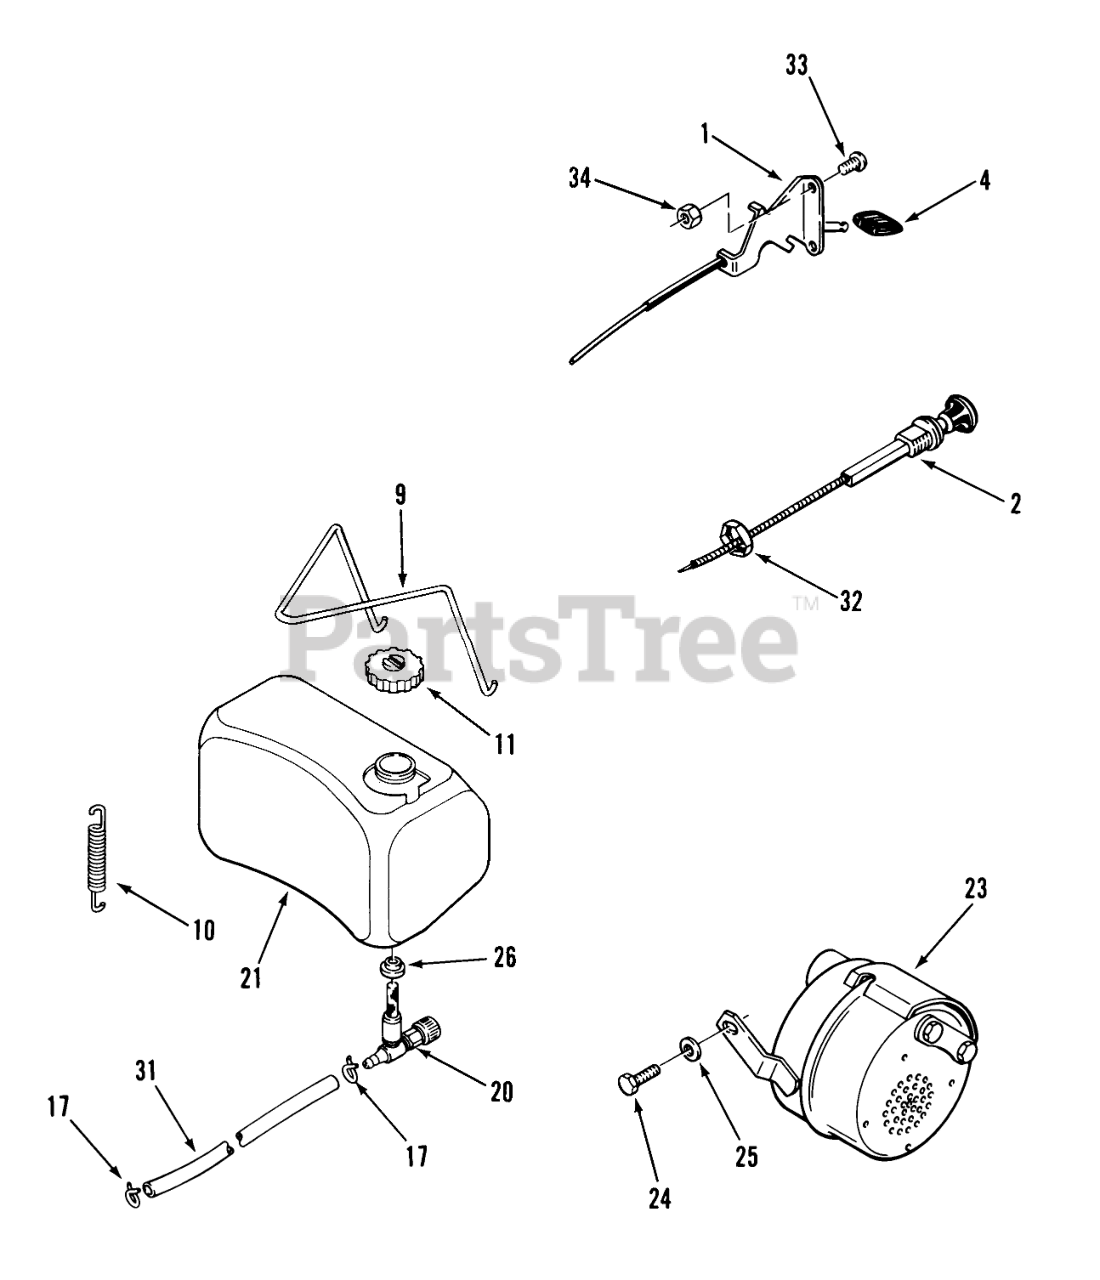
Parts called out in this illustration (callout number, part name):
1	CONTROL- THROTTLE
1	Choke/Throttle Control LT-1100 Only
2	CONTROL-CHOKE
4	KNOB-THROTTLE
9	Hold Down Wire
10	SPRING-EXTENSION
11	CAP-GASOLINE
17	Clamp
20	VALVE-FUEL
21	Fuel Tank Assy
23	ASSY-MUFFLER
24	Bolt
26	BUSHING
31	Fuel Hose 14.5 in. (36.8 cm) B-115 Only
31	Hose
32	NUT-HEX PALNUT
33	Screw
34	Nut
